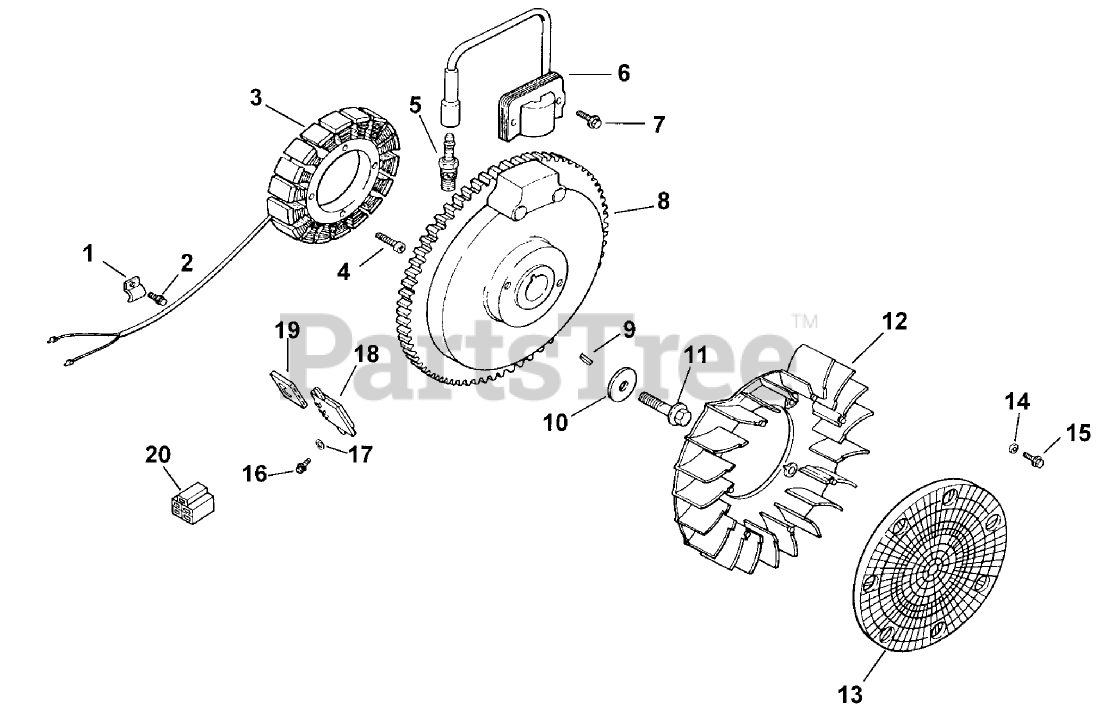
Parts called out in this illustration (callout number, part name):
1	Clip
2	Screw
3	Bracket-Wire, Stator
4	Screw
5	Spark Plug
6	Module, ignition
7	Screw
8	Flywheel
9	Key
10	Washer
11	Screw
12	Fan
13	Screen-Grass (Only On: 72042, 72063, 72062, 72043)
14	Spacer-Fan
15	Screw
16	Screw
17	Washer-Lock (Only On: 72042, 72063, 72062, 72043)
18	Rectifier-Regulator (Only On: 72042,72043,72062,72063)
19	Connector
20	Connector
